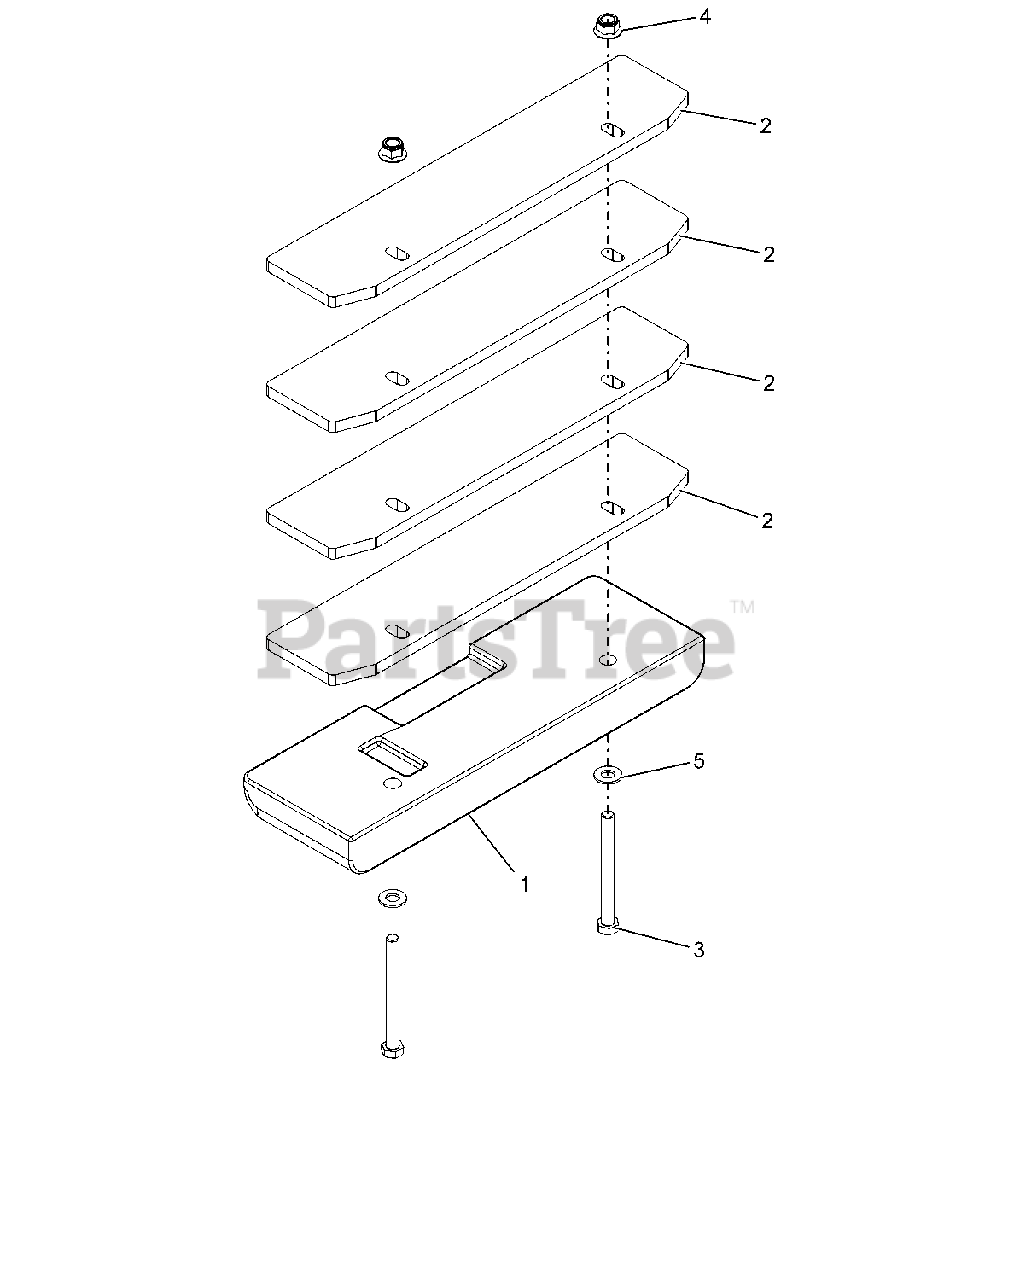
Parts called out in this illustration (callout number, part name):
1	WEIGHT, CAST IRON
2	WEIGHT, COUNTER
3	BLT-HEX .50-13X5.00 GR5 YWZC
4	NUT-LK-NYL-FLG .50-13 YWZC
5	WSHR-FL-STL.531X1.06X.095YWZC
